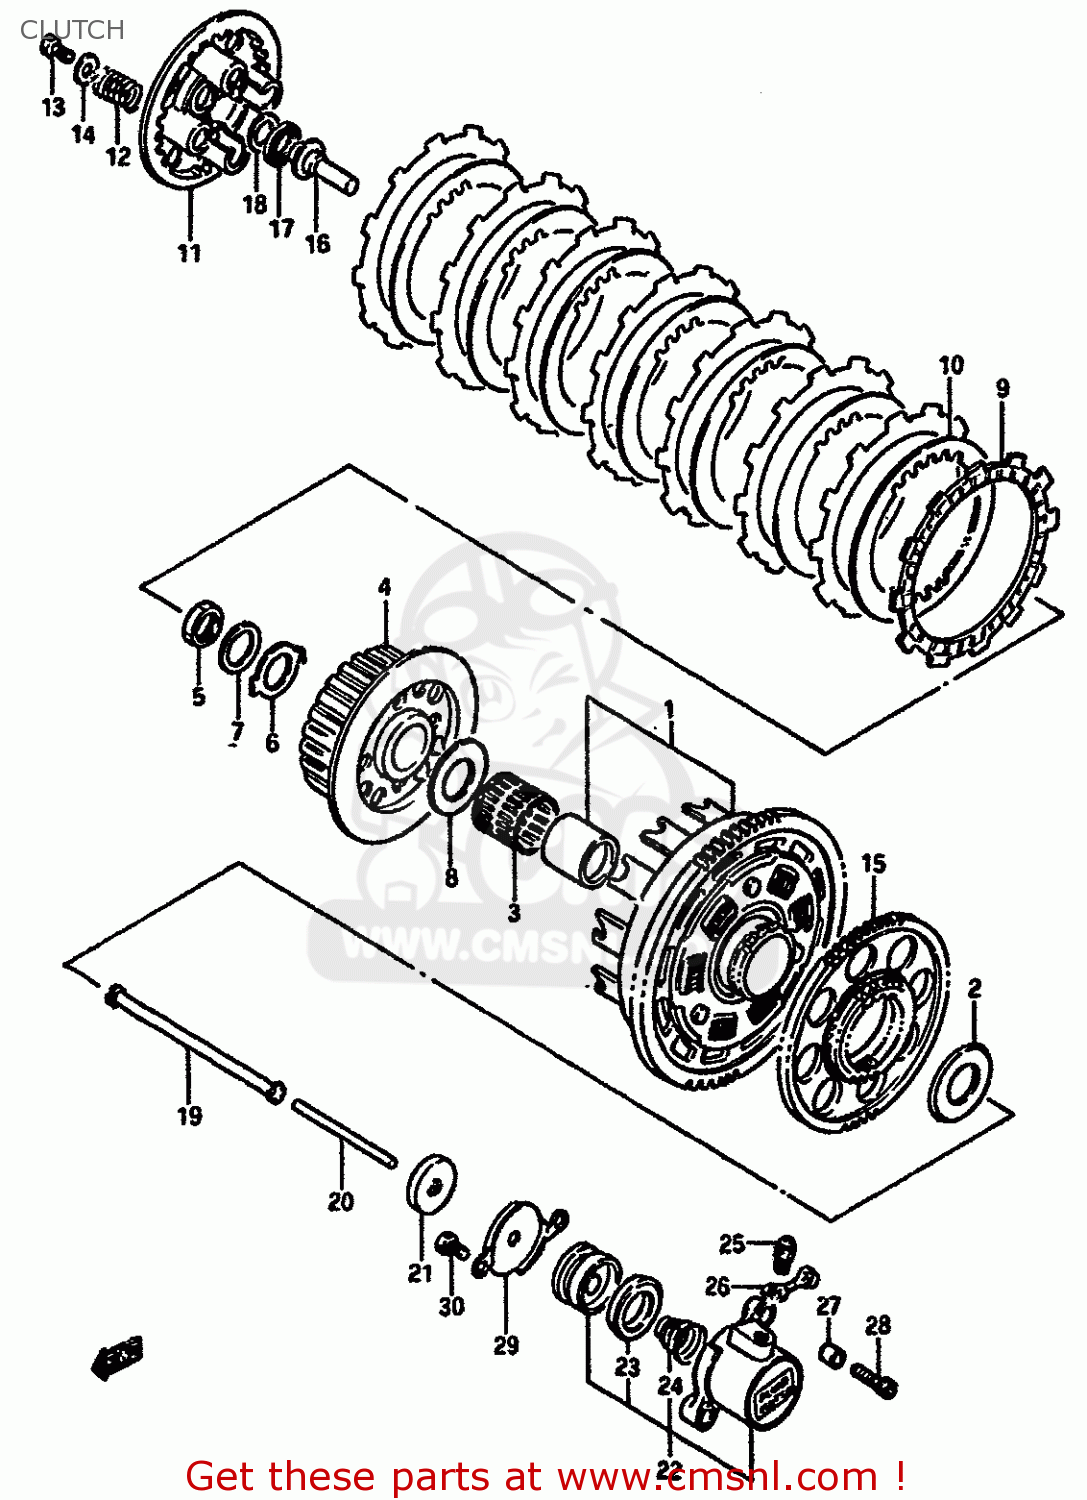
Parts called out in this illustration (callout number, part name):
1	GEAR,PRIMARY DRIVEN (NT:75)
2	WASHER
3	BEARING(35X40X35.8)
4	HUB,CLUTCH SLEEVE
5	NUT
6	WASHER
7	WASHER
8	WASHER(25X50X2.5)
9	PLATE,CLUTCH DRIVE (NAS)
10	PLATE,CLUTCH DRIVEN (NAS)
11	DISC,CLUTCH PRESSURE
12	SPRING
13	BOLT
14	WASHER
15	GEAR,GENERATOR DRIVE
16	PIECE,CLUTCH PUSH
17	BEARING(15X28X2)
18	WASHER
19	ROD,CLUTCH
20	ROD,CLUTCH PUSH,L
21	SEAL,OIL(6X34X5.5)
22	CYLINDER,CLUTCH RELEASE
23	CUP,CLUTCH CYLINDER
24	SPRING,CLUTCH CYLINDER
25	BLEEDER
26	CAP,BLEEDER
27	PIN
28	BOLT
29	PLATE,CLUTCH PUSH ROD
30	SCREW
